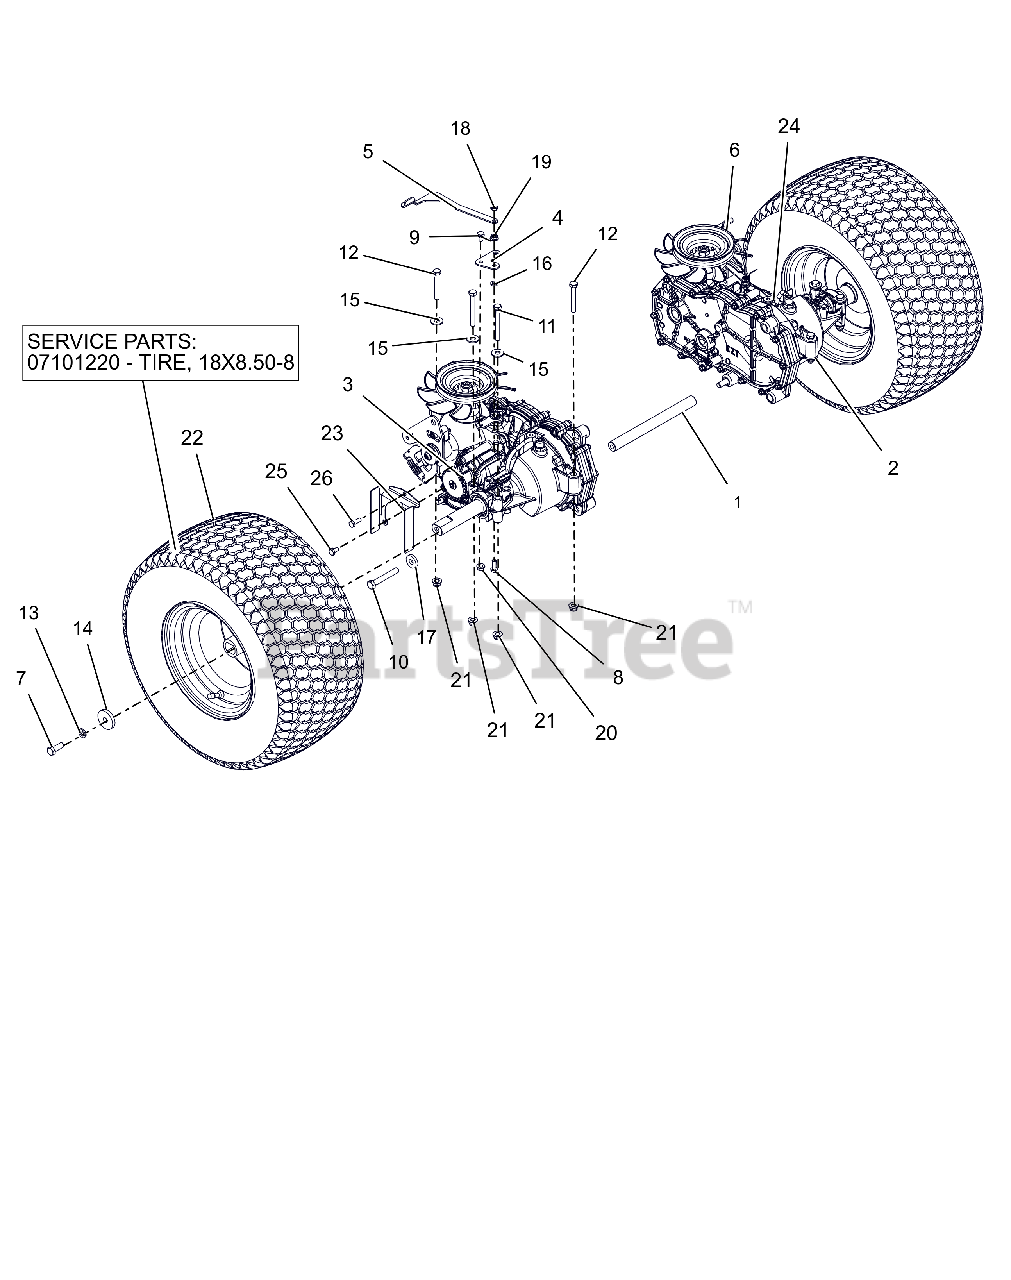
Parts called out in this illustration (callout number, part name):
1	ROD, TRANSAXLE BRACE
2	TRANSAXLE,LH EZT D-SHFT SHORT
3	TRANSAXLE,RH EZT D-SHFT SHORT
4	BRKT, DUMP VALVE EXTENSION
5	BRKT, DUMP VALVE RH
6	BRKT, DUMP VALVE LH
7	BLT-HEX .38-16X1.0 GR8 YZ EP30
8	@BLT-HEX .25-20X.75 GR5 YWZC
9	@BLT-HEX .25-20X.50 GR5 YWZC
10	@BLT-HEX .38-16X2.50 GR5 YWZC
11	@BLT-HEX .31-18X2.75 GR5 YWZC
12	@BLT-HEX .31-18X2.25 GR5 YWZC
13	@WSHR-LK .38X.094 REG YWZC
14	WSHR,FLT STL.406X1.50X.245YWZC
15	@WSHR-FL-STL.38X.875X.083 YWZC
16	WSHR-FL-STL .265X.50X.087YWZC
17	WSHR-FL-STL .406X1.00X.188 YWZ
18	NUT-LK-CTR JAM .25-20 YWZC
19	@NUT-SPNLK-FLG .25-20 YWZC
20	@NUT-LK-TOP-FLG .25-20 YWZC
21	@NUT-LK-NYL-FLG .31-18 YWZC
22	ASM, WHL/TIRE 18X8.50-8 DHUB
22	LAWN TIRE REAR, 4 PLY K500 18/8.50-8
23	GUARD, PARKING BRAKE RH
24	GUARD, PARKING BRAKE LH
25	@BLT-HEX .25-20X.50 GR5 YWZC
26	@BLT-HEX .25-20X.75 GR5 YWZC
